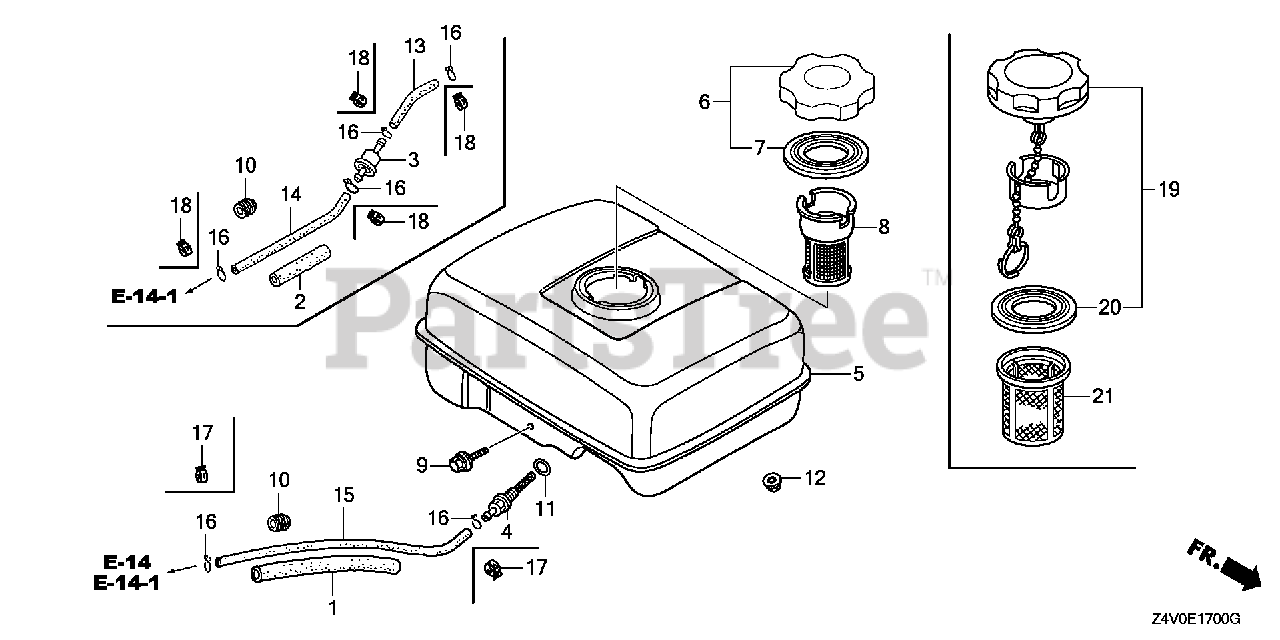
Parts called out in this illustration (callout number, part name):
1	RUBBER, SUPPORTER (107MM)
15	TUBE, FUEL (4.2X430) (FKM)
17	CLIP, TUBE (D8)
